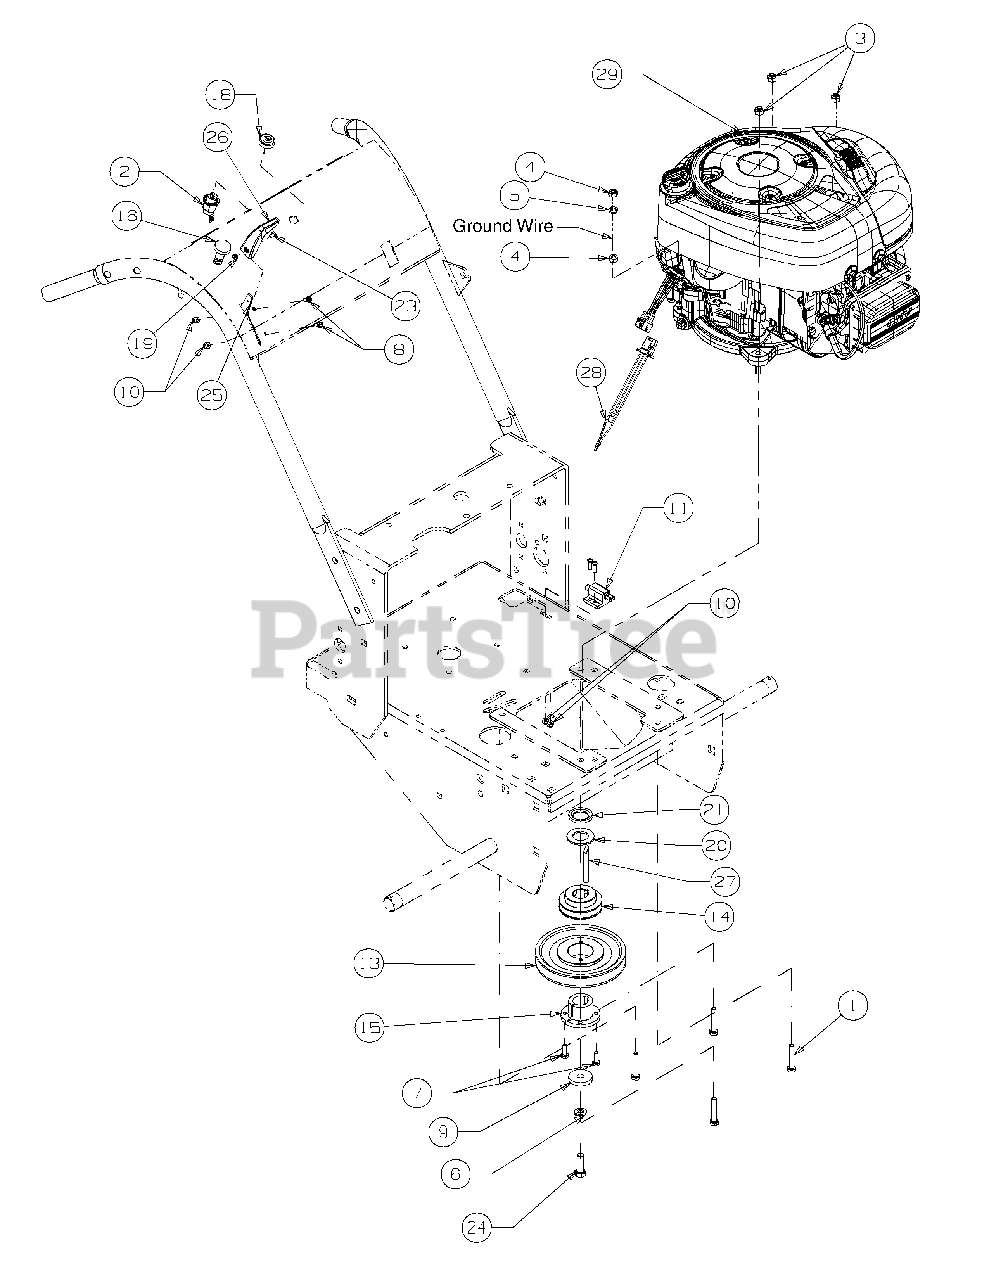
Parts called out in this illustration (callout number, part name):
1	Hex Cap Screw, 5/16-18 x 1-3/4
2	Single Ignition ON/OFF Switch
3	Nut, 5/16-18, Nylock
4	Hex Nut, 5/16-18
5	Lock Washer, 5/16 Zinc
6	Lock Washer, 7/16
7	Hex Cap Screw, 1/4-20 x 0.75
8	Screw, Hex Washer, 10-32 x 1/2
9	Clutch Washer
10	Lock Nut, Nylon Insert, 10-32
11	Delta Switch
13	Deck Pulley
14	Traction Pulley
15	Bushing
16	Choke Cable
17	Machine Screw, 10-32 x 5/8
18	Nut w/cap, 5/8-32 Ignition
19	Nut, 8-32, w/Star Washer
20	Flat Washer
21	Spacer, Engine Pulley
23	Screw, 8-32 x 0.375
24	Hex Cap Screw, 7/16-20 x 1-1/4
25	Throttle Cable
26	Throttle Control Knob
27	Key Stick, 1/4 x 1/4 x 2-3/4
28	Harness Adaptor
29	12.5 Hp Briggs Engine
